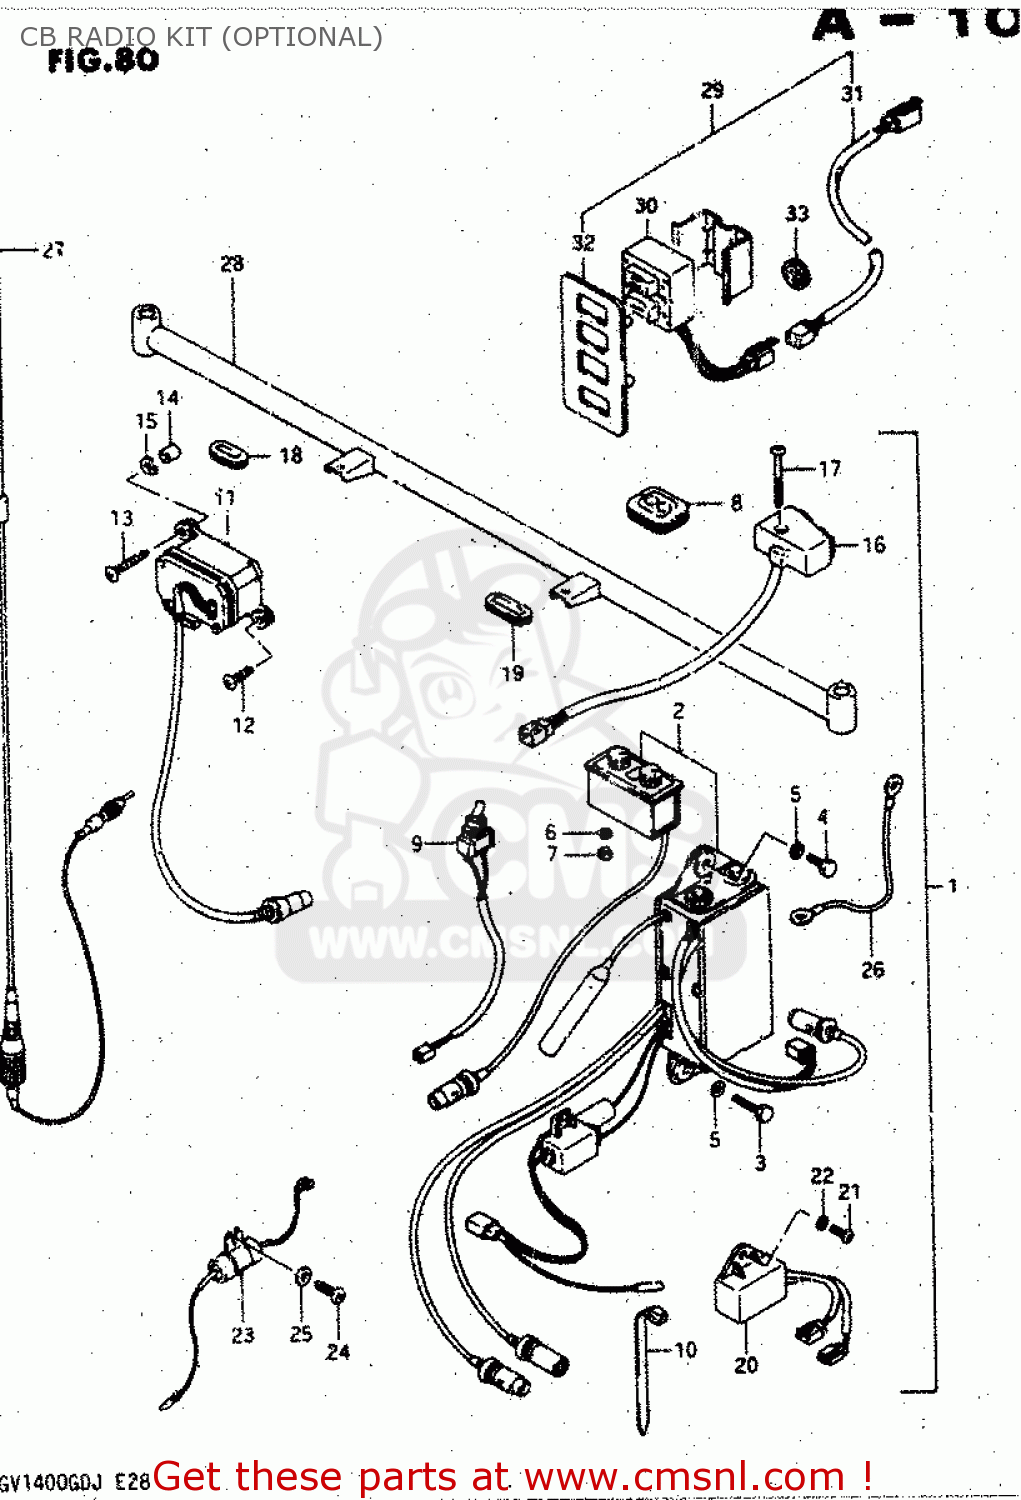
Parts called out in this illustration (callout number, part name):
1	CB RADIO KIT
2	CB TRANSCEIVER SET
3	BOLT
4	BOLT
5	LOCK WASHER
6	LOCK WASHER
7	NUT M4 DIN 985
8	GROMMET
9	SWITCH ASSEMBLY,CB BACK UP
10	CLAMP(L:100)
11	INDICATOR ASSEMBLY,CB CHANNEL
12	SCREW
13	SCREW
14	SPACER (5.2X8X12.5)
15	WASHER (4X16X1.2)
16	SWITCH ASSEMBLY,CB CHANNEL SELECT
17	SWITCH
18	CROMMET, NO.1
19	GROMMET
20	FILTER,FAN MOTOR NOISE
21	SCREW
22	WASHER
23	CONDENSER,CB UNIT
24	SCREW
25	WASHER
26	WIRE
27	ANTENNA ASSY,CB TRANSCIVER
28	HOLDER,ANTENNA BAR
29	CB CO-RIDER REMOTE CONTROL SWITCH
30	SWITCH
31	WIRE,CB SELECT SWITCH
32	PANEL,TUNER ASSEMBLY NO
33	GROMMET, WIRE
